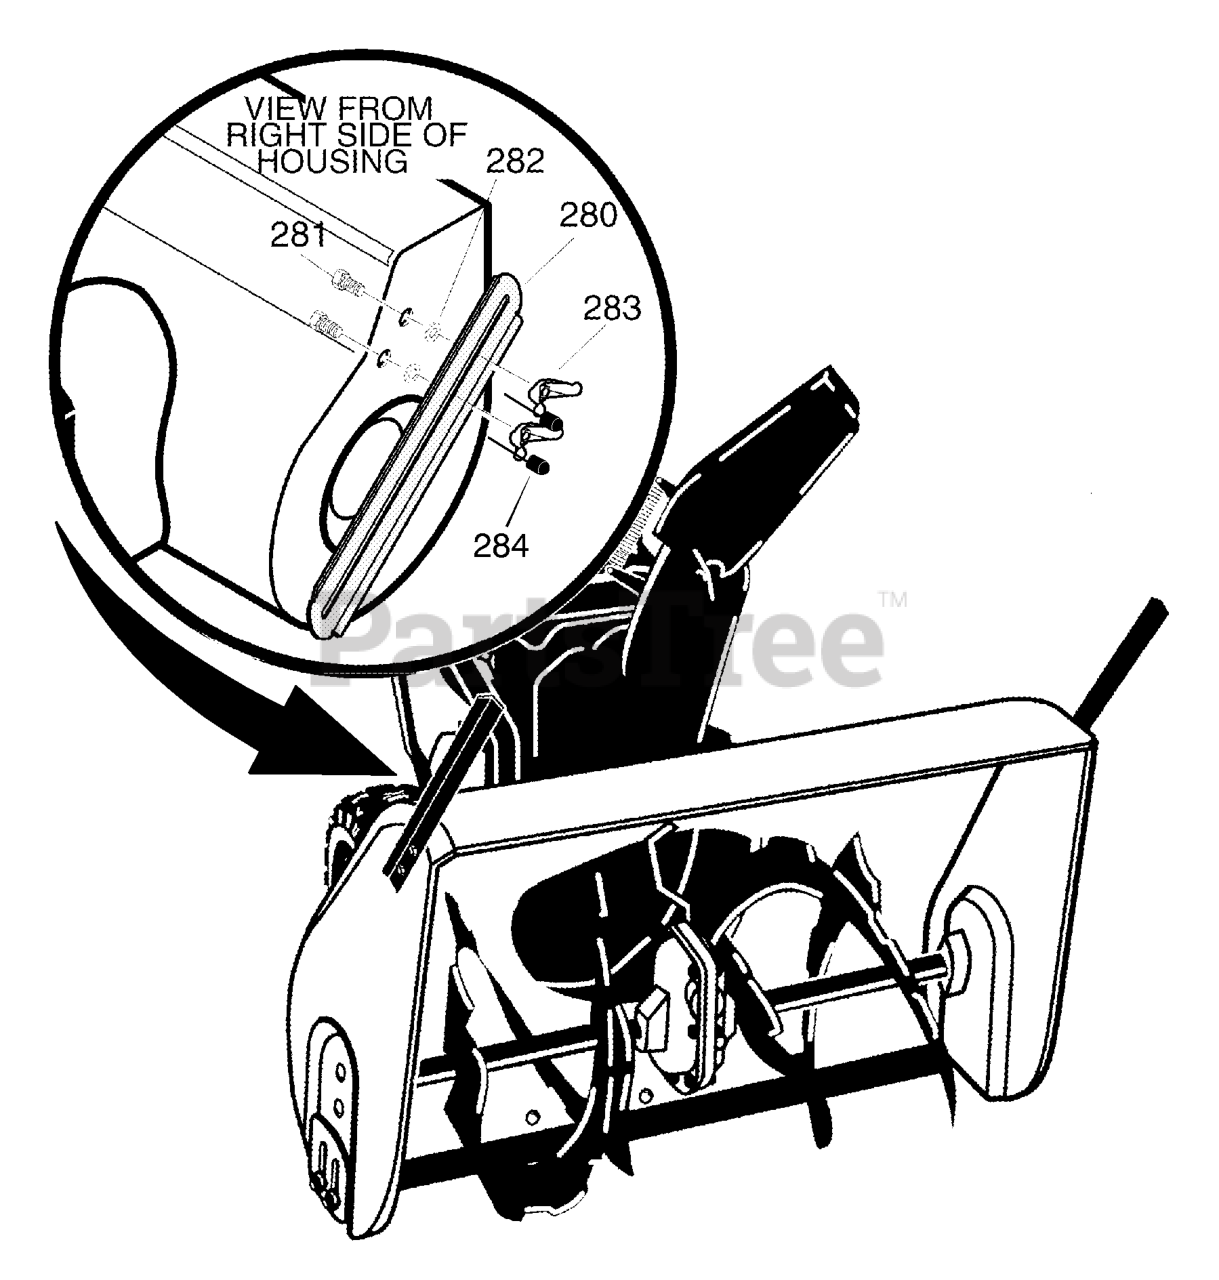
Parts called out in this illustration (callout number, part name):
280	DRIFT CUTTER
281	BOLT
282	WASHER
283	WINGNUT
284	STOP, PLASTIC
